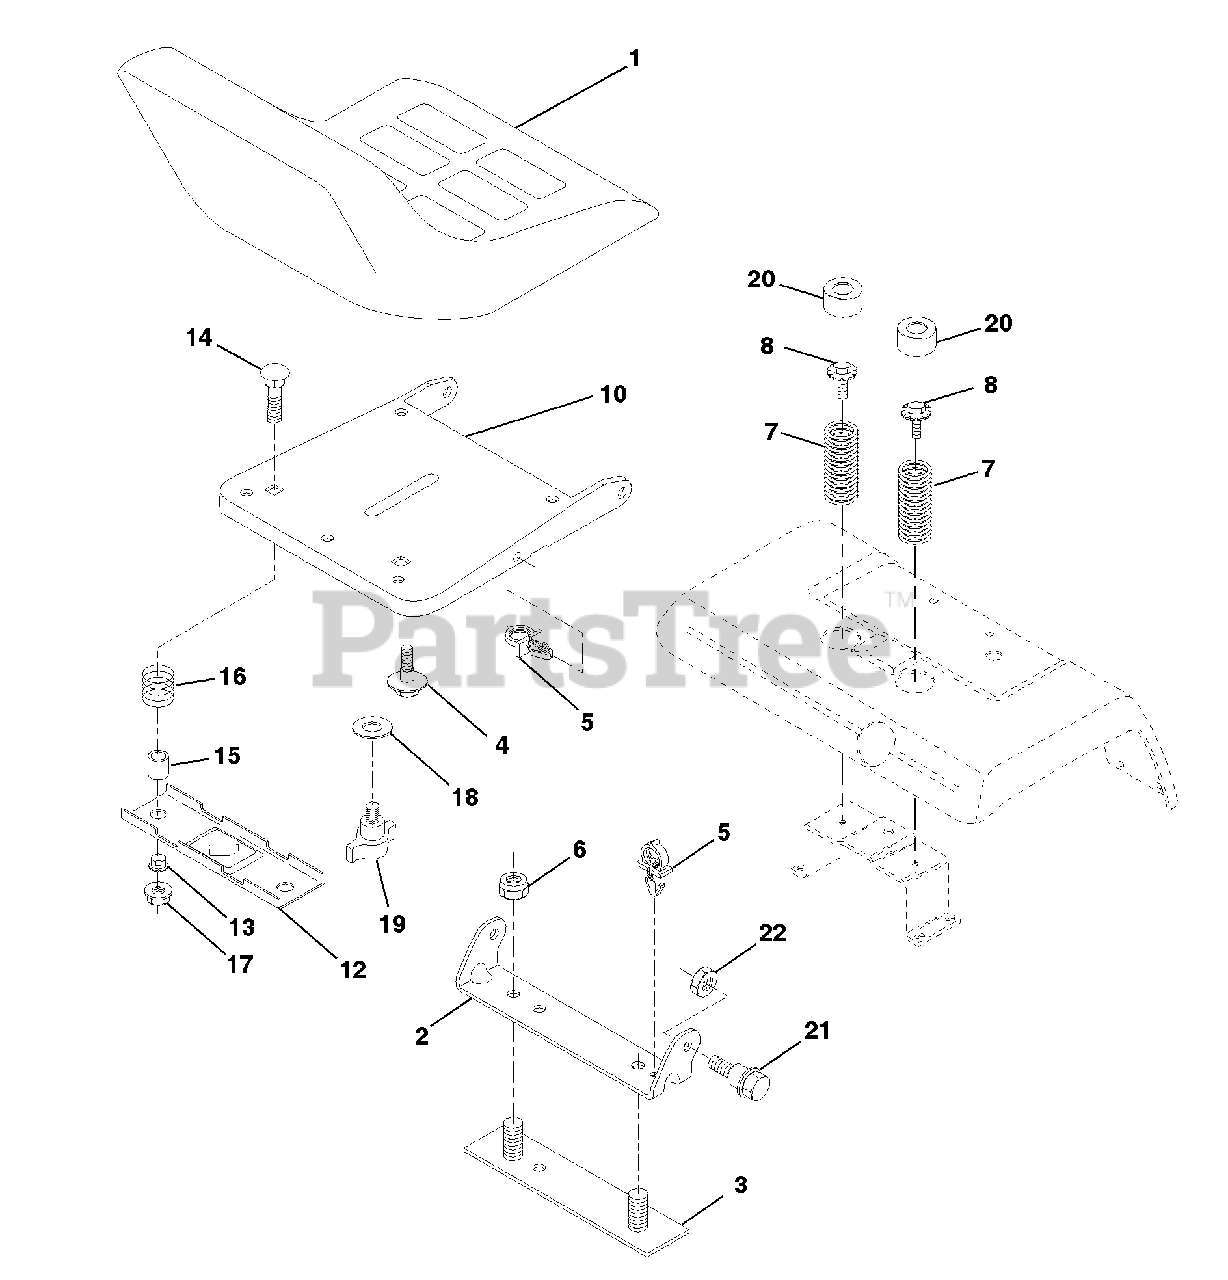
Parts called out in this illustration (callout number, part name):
1	Seat
2	Bracket, Pivot Seat
3	Strap, Fender
4	Bolt, Shoulder 5/16-18 X .62
5	Clip, Push In Hinged
6	Nut, Lock Hex W/Ins. 3/8-16 Unc
7	Spring, Seat Cprsn
8	Bolt 5/16-18unc x 3/4 W/Sems
10	Pan, Seat
12	Bracket, Mounting Switch
13	Bushing, Snap
14	Bolt, Carriage 1/4-20 X 1-1/2
15	Spacer, Split
16	Spring, Cprsn
17	Nut, Lock 1/4 Lge Flg Gr. 5
18	Washer 17/32 X 1-3/16 X 12 Ga.
19	Knob, Seat 1/2-13 Unc
20	Cap, Spring Seat
21	Bolt, Shoulder 5/16-18 Unc-2A
22	Nut, Crownlock 5/16-18 Unc
